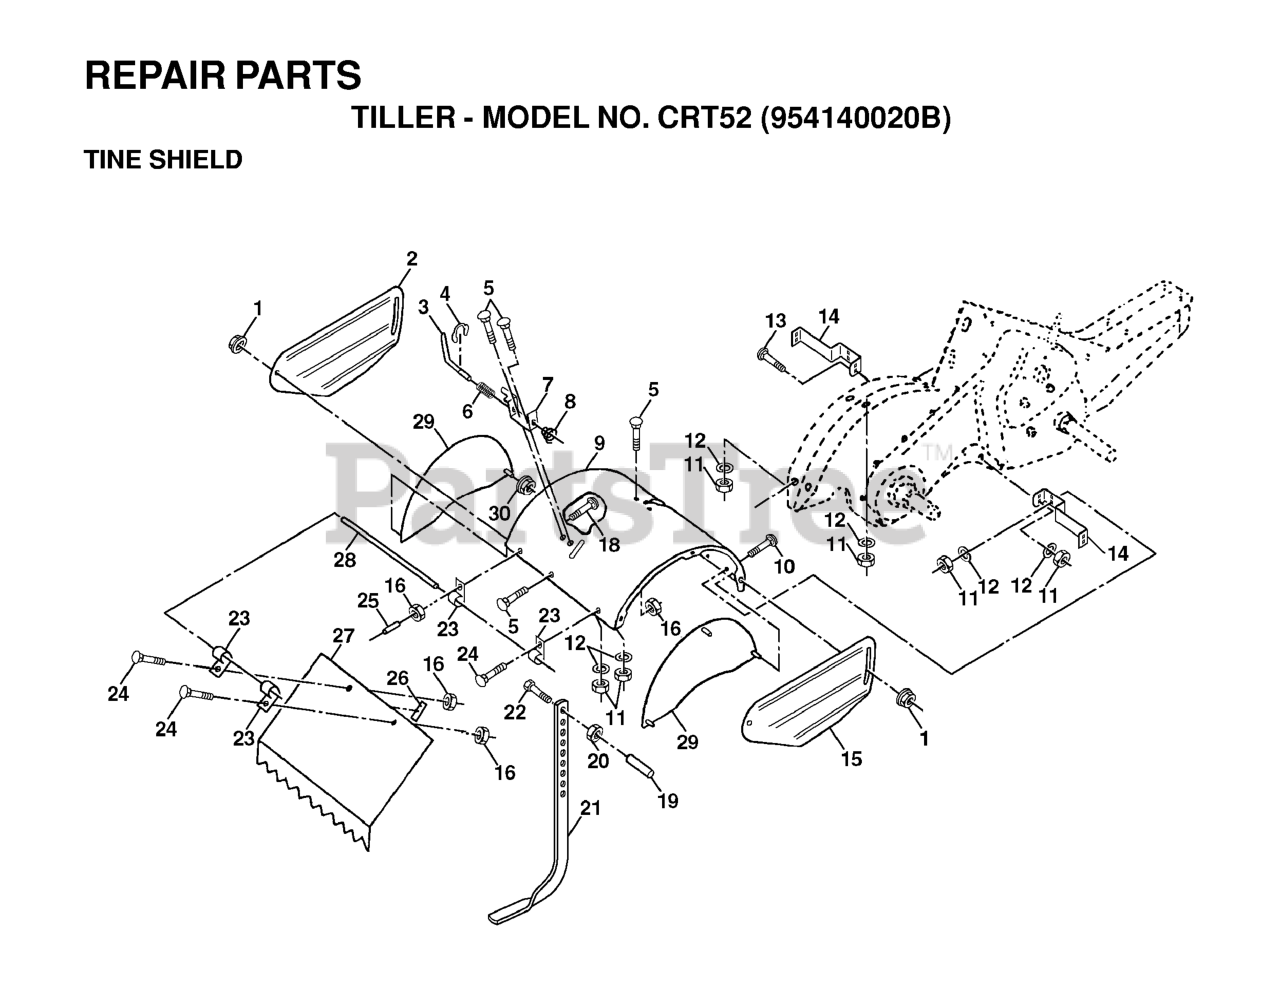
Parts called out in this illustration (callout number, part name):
2	KEY, 1/4 SQ X 1 1/4
7	HUB.PNT.GT.PM.1IN.AXLE.E-DIP
15	WASHER
17	SPRING.BRAKE.HG3000/3500
26	SPRING.RETURN.CRUISE
33	E RING HYT
35	ROD ROD.PARKINGBRAKE.GT.HUSQ/P
42	PEDAL COVER
50	IDLER.FLAT.910.OFFSET
51	NUT LOCK FLG 3/8-16 UNC
52	IDLER.V-GROOVE.910.OFFSET
64	SHAFT.ASM.PEDAL.BRK.CNTR
70	CONSOLE.ASM.RH.GT.FC.HUSQ
73	BOLT HEX FLGHD 5/16-18X3 GR. 5
74	SCREW.HI-LO.CONSOLE
80	STRAP.TORQUE.YT.G700
92	BOLT
99	ROD ASSY BYPASS G730
114	NUT.71038.31-18.HEX.NYLOCK
116	NUT LOCK HEX FLANGE 5/16-18
121	BRACKET STRAP TORQUE
125	SCREW
145	WASHER.AXLE.FLANGE.HG-3000
153	RETAINER M
159	COTTER PIN
160	RETAINER CLIP
161	SPRING, RETURN LT
163	ROD PEDAL CONTROL
166	NUT.PUSH.625
167	LATCH.BRAKE.SPRING
170	KEEPER.V-IDLER.CENTER.
183	SPACER.SPLIT.1.000ID X 1.500
184	HANDLE.PARKING.BRAKE.H (BLK)
186	SPACER.RETAINER
187	WASHER 12/32X2X10GA
188	LINK.CLUTCH.GROUND DRIVE.LONG
189	BELLCRANK.GROUND.DRIVE.TEX.
190	KEEPER.BELLCRANK.DRIVE
196	SCREW 3/8-16X1
197	CLUTCH.ANTIROTATION.WIREFORM.
203	WASHER
206	BRACKET.MOUNT.CRUISE.LATCH
207	LATCH.CONTROL.CRUISE.TEX
208	GEAR.SECTOR.CONTROL.CR
209	ROD ROD.CRUISECONTROL.GT.HUSQ/
210	ROCKER.ASM.PEDAL.CONTR
211	BEARING.NYLON
213	KNOB.CONTROL.CRUSIE.HU
214	PEDAL.FORWARD.PAD.TEX
215	PEDAL.COVER.REVERSE.CRD.X428BK
220	REFLECTOR.RH.TEX GT
221	RETAINER.SPRING.CLIP.H
222	WASHER 21/32 X 1-1/4 X 10 GA.
286	BOLT.5/16-18X2.5
306	PIN COTTER
